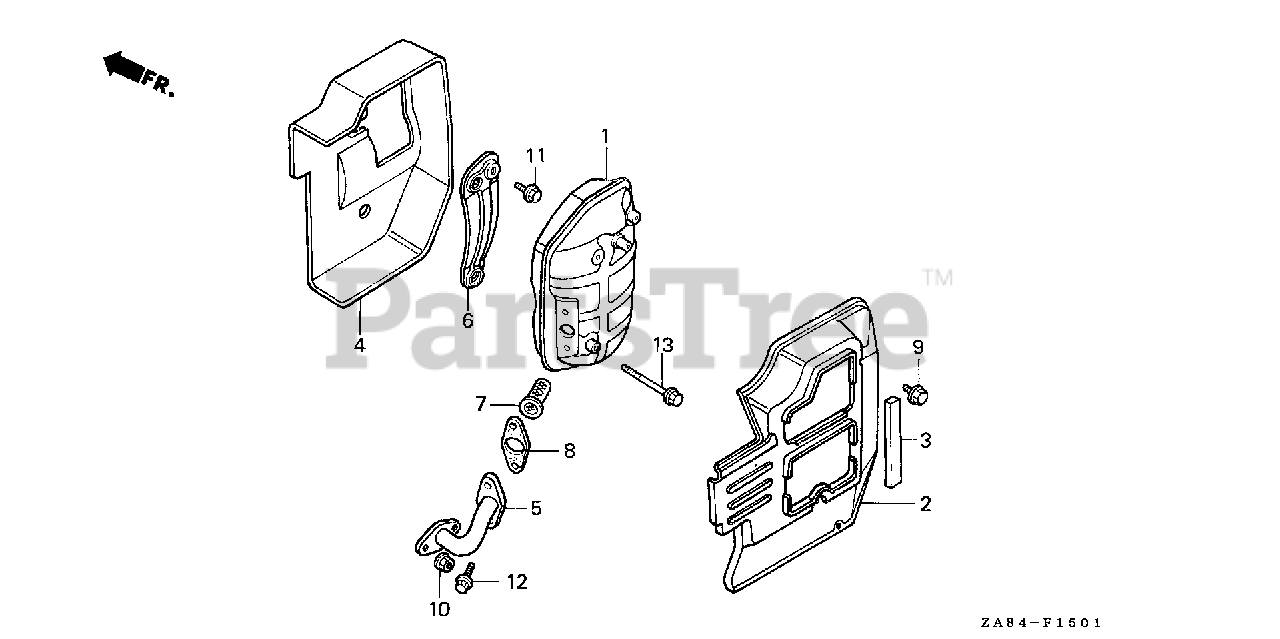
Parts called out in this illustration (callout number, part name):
2	PROTECTOR, MUFFLER
3	SEAL, MUFFLER (OUTER)
4	SEPARATOR, GLASS WOOL
6	BRACKET, MUFFLER
7	ARRESTER, SPARK
8	GASKET, MUFFLER
9	BOLT, FLANGE (6X8)
10	NUT, FLANGE (6MM)
11	BOLT, FLANGE (6X12)
12	BOLT, FLANGE (6X16)
13	BOLT, FLANGE (6X65)
